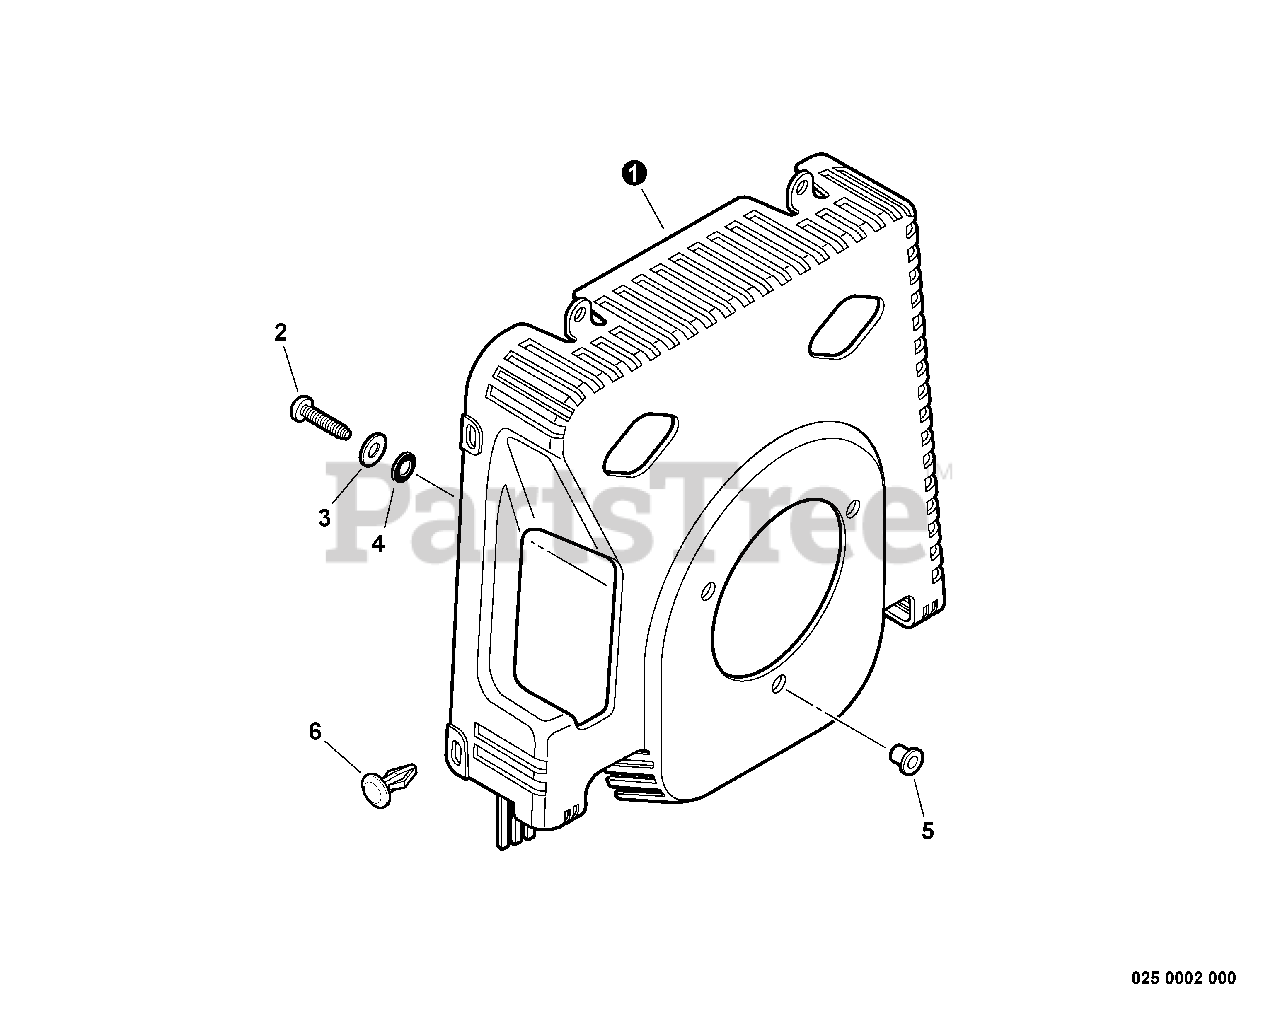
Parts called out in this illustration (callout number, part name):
1	GUARD, DEBRIS
2	SCREW, TAPPING 5×20
3	WASHER 5.5×16×2T
4	WASHER - RUBBER
